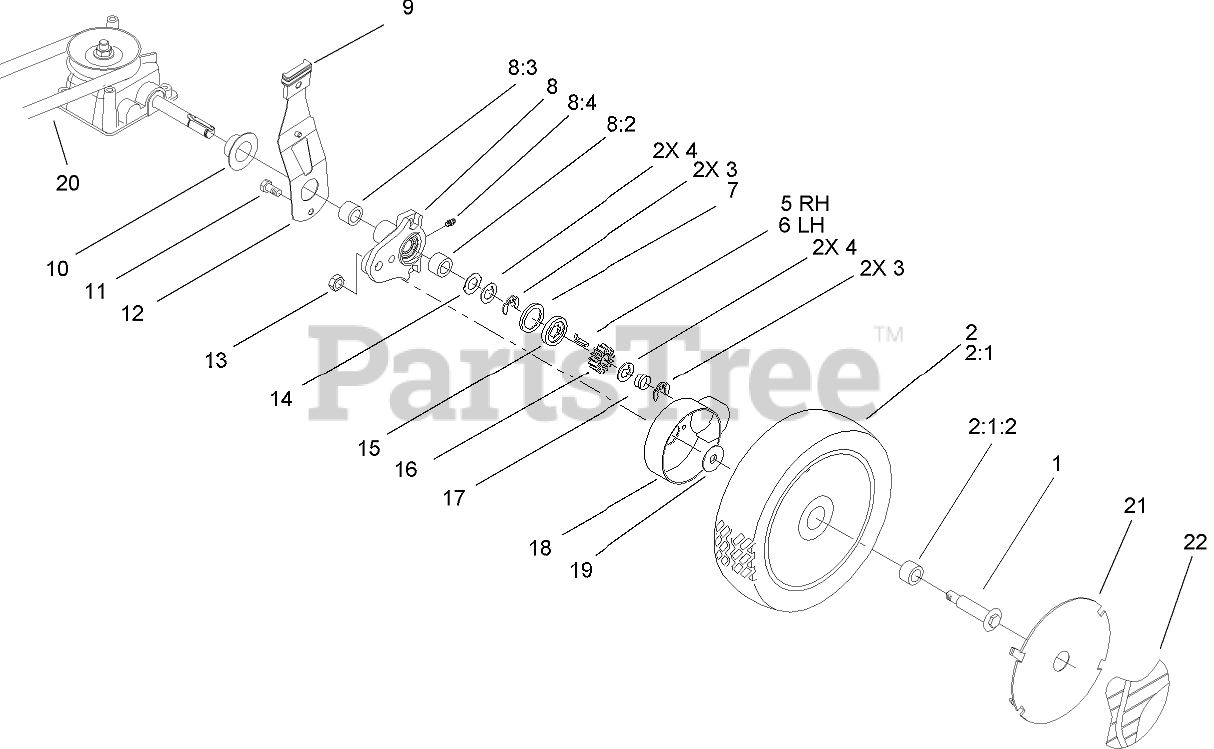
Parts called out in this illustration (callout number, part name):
1	BOLT-SHOULDER
2	WHEEL ASM
2:1	Wheel ASM
2:1:2	BUSHING
3	RING-CLIP, LOCKING
4	WASHER-THRUST, KEYED
5	KEY-ROCKING, RH
6	KEY-ROCKING, LH
7	RING-FRICTION
8	PIVOT ARM ASM
8:2	BUSHING
8:3	BUSHING
8:4	FITTING-GREASE
9	KNOB-ARM
10	CAP-END
11	SCREW-HWH
12	SPRING ARM ASM
14	WASHER-ARM, PIVOT
15	WASHER-CLUTCH
16	GEAR-PINION
17	SPRING-COMPRESSION
18	COVER-WHEEL
19	SPACER-COVER, WHEEL
20	BELT-V
21	COVER-WHEEL
22	LABEL-WHEEL, SMART
